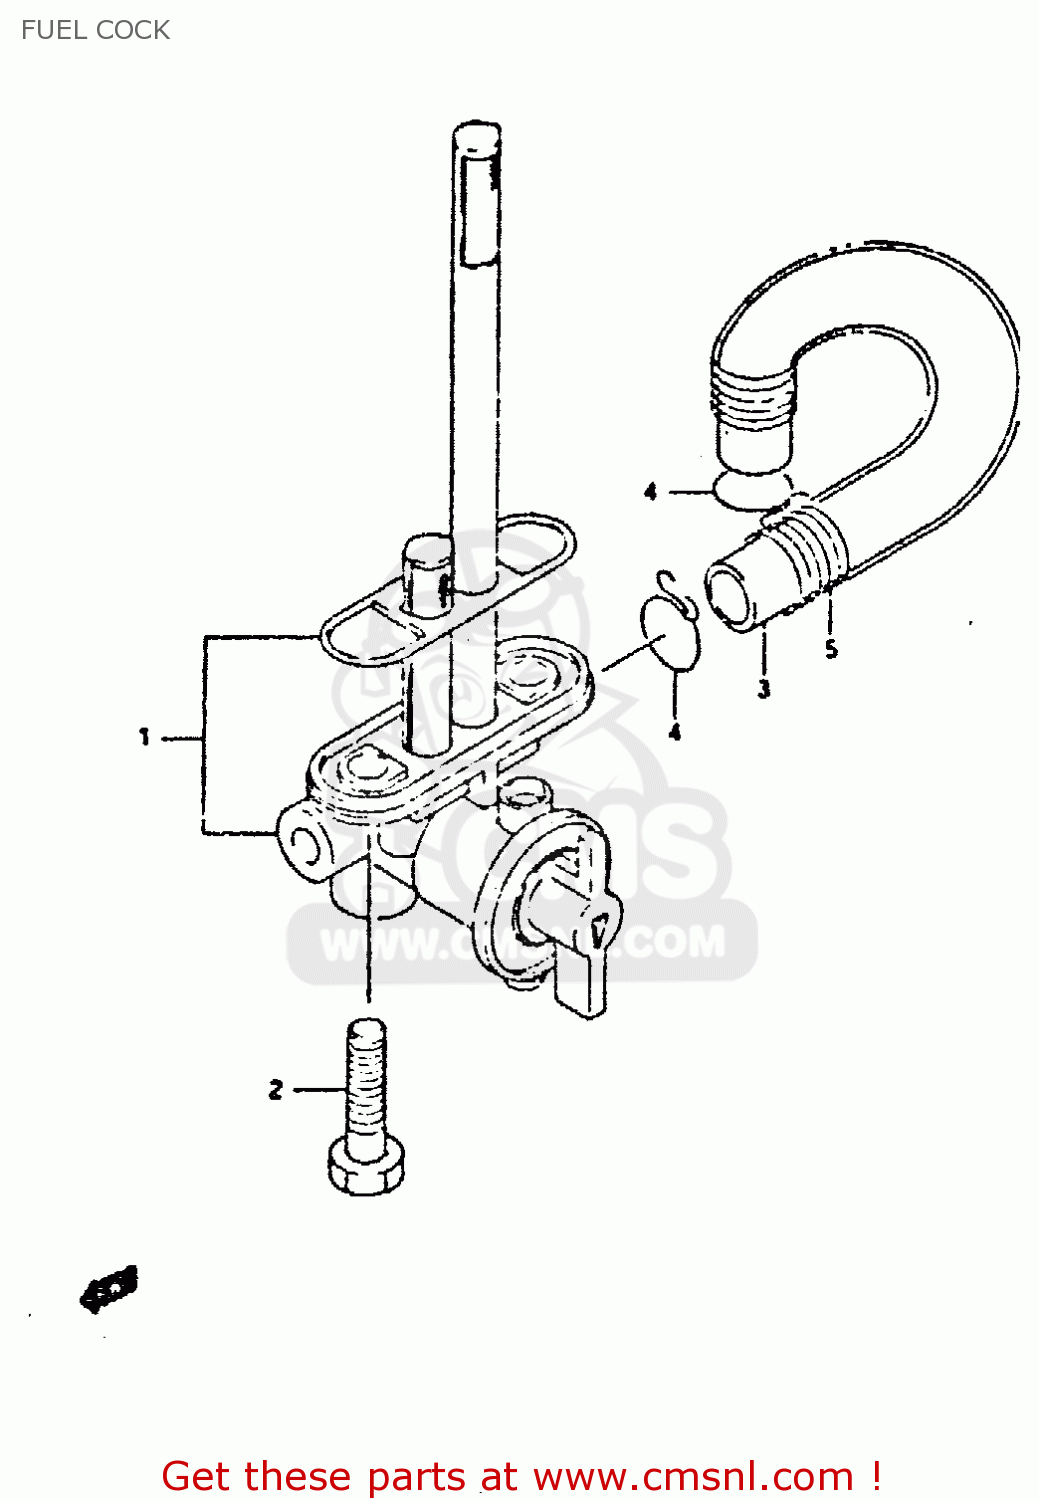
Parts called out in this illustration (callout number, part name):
1	COCK ASSY,FUEL
2	SCREW
3	HOSE(7X10.2X600)
4	CLIP
5	SPRING
